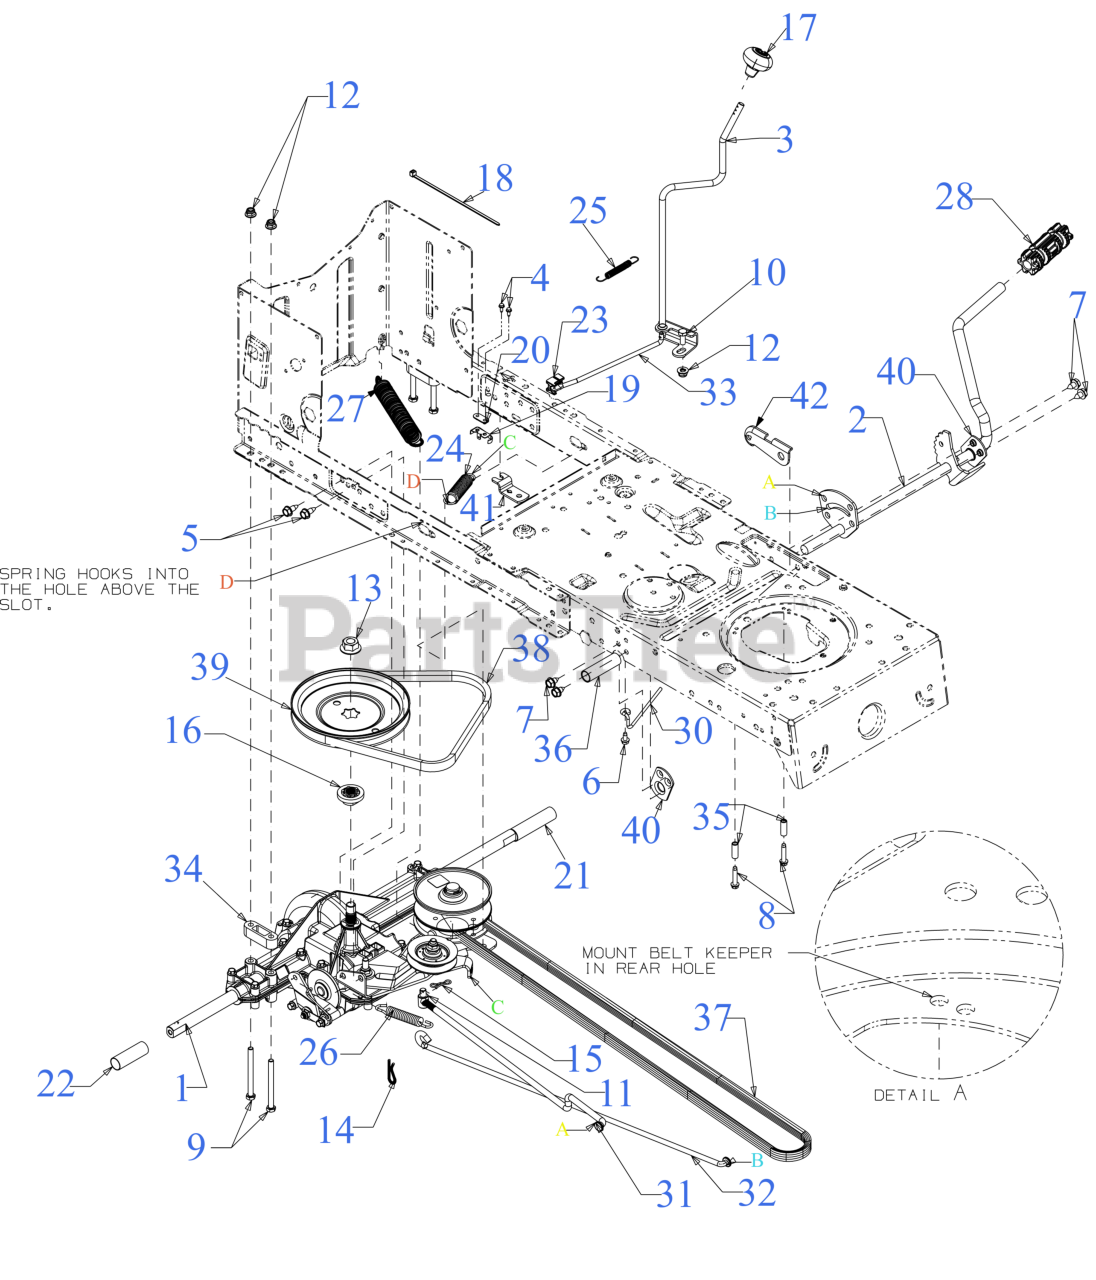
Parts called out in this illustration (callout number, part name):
1	TRANSAXLE
1	TRANSMISSION PULLEY
1	SCREW 5/16-18 x .750
3	SHIFT LEVER ASSEMBLY
4	HEX SCREW WASHER HD #8-18 x 0.500
5	SCREW 5/16-18 x .750
6	SCREW 1/4-20 X.500
7	SCREW 5/16-18 x .625
8	SCREW 1/4-20 x 1.25
9	SCREW 5/16-18X3.5 GR5
10	SCREW 5/16-18 x .75 GR5
11	FERRULE 3/8-24 x .375
12	FLANGE LOCK NUT 5/16-18
13	FLANGE NUT W/HUB
14	COTTER PIN
15	BOW TIE COTTER PIN 1/4-5/16
16	PULLEY HUB
17	SHIFT KNOB
18	7" CABLE TIE
19	SAFETY SPRING SWITCH
20	INSULATOR NUT PLATE
21	SLEEVE
22	SLEEVE
23	SHIFT ROD BEARING
24	EXTENSION SPRING
25	EXTENSION SPRING .38 OD x 3.25 LG
26	EXTENSION SPRING
27	EXTENSION SPRING 1.08 DIA x 7.37
28	BRAKE PEDAL PAD
30	BELT KEEPER ROD
31	VARIABLE SPEED ROD
32	BRAKE ROD
33	SHIFT ROD
34	TRANSAXLE SPACER
35	SPACER
36	SPACER-5/8 ID x 2.
37	V-BELT 70.90"
37	Troy-Bilt TRANSMISSION DRIVE BELT
38	V-BELT 5L x 35.25
38	Troy-Bilt TRANSMISSION DRIVE BELT (-05040)
39	V-PULLEY W/HUB 7.25 DIA
41	SHIFT ADJUSTMENT BRACKET
42	LATCH SPEED BRACKET
